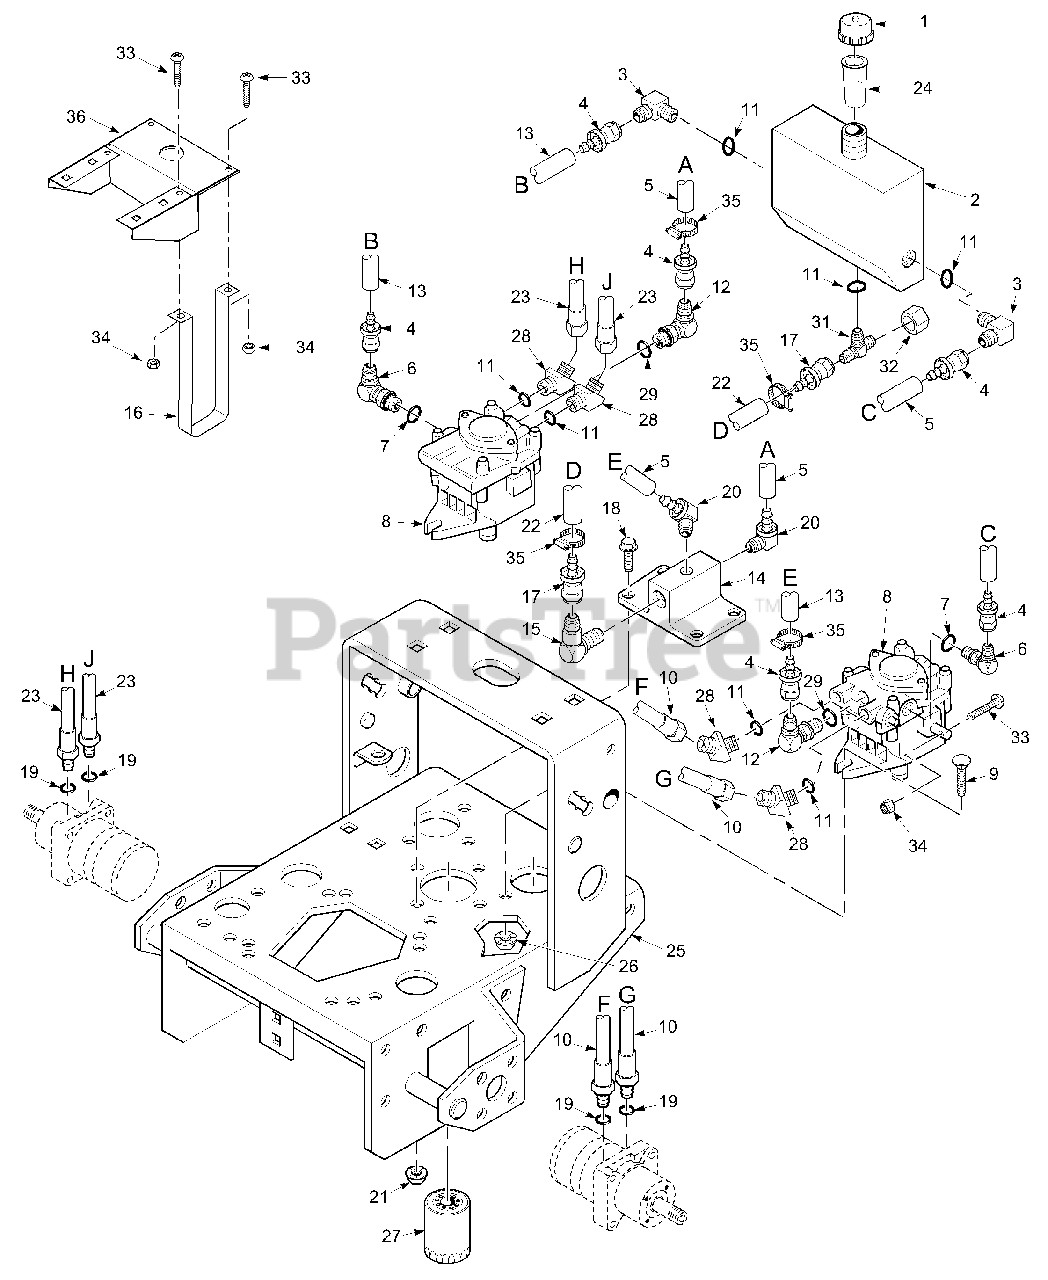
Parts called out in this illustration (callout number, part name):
1	Cap, Oil Reservoir
2	Oil Reservoir (With Fittings)
3	Elbow, 90 deg. 7/16-20 x 9/16-18
4	Coupling, 7/16-20 SAE Flare Swivel to 1/4" Hose Push On
5	Hose, 1/4" ID - 7" Long
6	Elbow, 90 deg. 7/16-20 JIC to 9/16-18 "O" Ring
7	O-Ring
8	Pump, Hydro-Gear BDP-10L117
9	Bolt, Carriage, 3/8-16 x 1.25"
10	Hose, Pump to Wheel Motor
11	O-Ring
12	Elbow, 90 deg., 1/2 NPT
13	Hose, 1/4" ID - 5" Long
14	Oil Filter Base
15	Elbow, 90 deg. 1/2" NPT
16	Strap, Hydraulic Tank
17	Coupling, 3/4-16 SAE to 1/2" Hose Push On
18	Capscrew, 5/16-18 x .75" Serr. Flange
19	O-Ring
20	Elbow, 90 deg. Male 1/4 NPT to 1/4 Hose Push On
21	Nut, 5/16-18 Serr. Flange
22	Hose, Formed 1/2" ID
23	Hose, Pump to Wheel Motor
24	Tube, Filler Neck
25	Engine Deck (16" Wide) W/Decals - Small Frame
26	Nut, 3/8-16 Serr. Flange
27	Oil Filter
28	Elbow, 45 Deg.-3/4-16 JIC Male x Male 3/4-16 O-Ring
29	O-Ring
31	T-Fitting, 1/2 (3/4-16)
32	Cap, 3/4-16
33	Screw, 1/4-20 x 2.0" Round Head Phillips
34	Nut, 1/4-20
35	Clamp, .87 max dia.
36	Bracket, Hydraulic Tank
